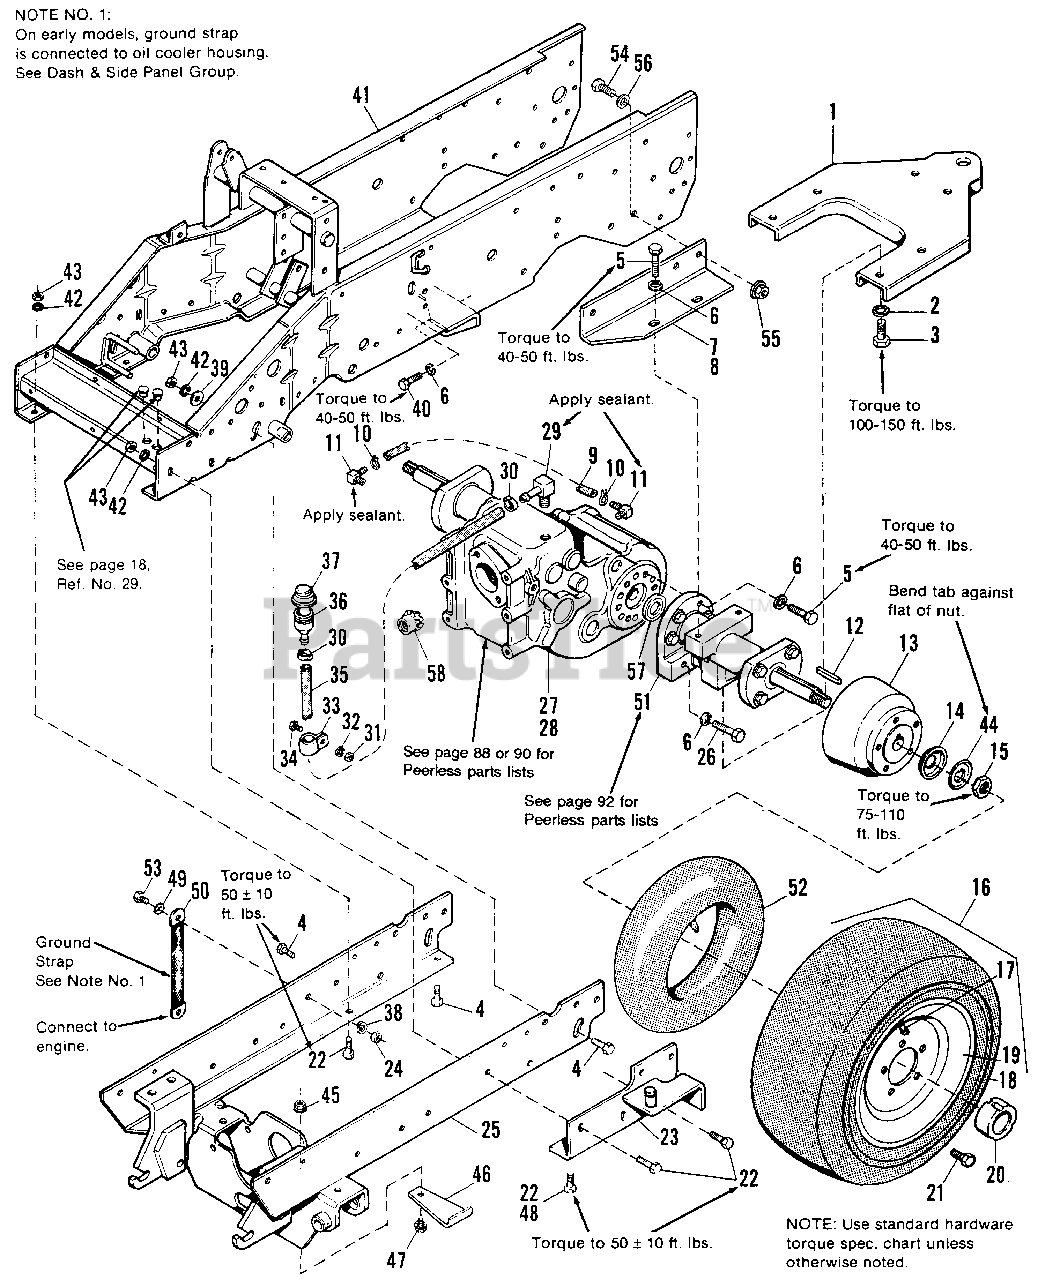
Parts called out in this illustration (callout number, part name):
2	LOCKWASHER, 5/8"
3	CAPSCREW, Hex Hd., 5/8-11 x 1-1/4
4	CAPSCREW, Hex Hd., 7/16-14 x 1, Gr. 5 (Qty. 11 on 1691018, 1691381, 1691528, 1691924)
5	CAPSCREW, Hex Hd., 1/2-13 x 1-1/2
6	LOCKWASHER, 1/2
7	SUPPORT, Transmission, R.H.
8	SUPPORT, Transmission, L.H.
9	HOSE, Fluid Level
10	CLAMP, SAE #6
11	FITTING, Elbow
12	KEY, 5/16 x 5/16 x 2-1/2
13	DRUM, Brake
14	RETAINER, Hub Cap
15	NUT, Hex, Jam Centerlock 1-14
16	WHEEL & TIRE ASSY., 23 x 10.5-12 (Incl. 2 Ref. Nos.17, 18 & 19) (All models except 1691250, 1691357, & 1691953)
16	WHEEL & TIRE ASSY., 23 x 8.5- 12 (Inc. Ref. Nos. 17, 18 & 19) (1691250 & 1691357 only)
16	WHEEL & TIRE ASSY., 26 x 12.00-12 (Inc. Ref. Nos. 17, 18 & 19) (1691953 only)
17	VALVE STEM & CAP
18	TIRE, Turf, 23 x 10.5-12 (All models except 1691250, 1691357 & 1691953)
18	TIRE, Turf, 23 x 8.5-12 (1691250 & 1691357 only)
18	TlRE, Turf, 26 x 12.00-12 (1691953 only)
18	TIRE, Bar Tread (Ag), RH, 26 x 12.00-12 (use only w/60" mower)
18	TIRE, Bar Tread (Ag), LH, 26 x 12.00-12 (use only w/60" mower)
19	WHEEL (all models except 1691953)
19	WHEEL (1691953 only)
22	CAPSCREW, Hex Hd., 7/16-14 x 1-1/4, Gr. 5 (Qty. 5 on 1691018, 1691381, 1691528, 1691710, 1691924, 1691926, 1691928, 1691953 only)
23	BRACKET ASSY., Power Steering Cylinder (Power Steering Models Only)
24	NUT, Hex, 3/8-16 (1691017 & 1691018 only)
25	FRONT FRAME ASSY.
26	CAPSCREW, Hex Hd., 1/2-13 x 2
29	FITTING, Hose, 90
30	CLAMP, Hose, Worm Drive, SAE #10
31	NUT, Hex, 1/4-20
32	LOCKWASHER, 1/4
33	CLAMP, Insulated
34	CAPSCREW, Hex Hd., 1/4-20 x 3/4
35	HOSE, Fill, 1/2" I.D.
36	NECK, Filler
37	CAP, Filler
38	LOCKWASHER, 3/8 (1601017, 1691018 only)
39	WASHER, Plain, 1/2 (1691018, 1691381, 1691528, 1691710, 1691924, 1691926, 1691928, & 1691953 only)
40	CAPSCREW, Hex Hd., 1/2-13 x 1-1/4
41	FRAME ASSY., Rear
42	LOCKWASHER, 7/16 (Qty. 11 on 1691018, 1691381, 1691528, 1691710, 1691924, 1691926, 1691928, 1691953)
43	NUT, Hex, 7/16-14 (Qty. 11 on 1691018, 1691381, 1691528, 1691710, 1691924, 1691926, 1691928, 1691953)
44	RETAINER NUT
45	NUT, Whizlock 3/8-16 (1691017 & 1691018 only)
46	STOP, Axle (1691017 & 1691018 only)
47	SCREW, Whizlock 3/8-16 x 1 (1691017 & 1691018 only)
48	CAPSCREW, 7/16-14 x 1-1/2 (1691018, 1691381, 1691528, 1691710, 1691924, 1691926, 1691928, 1691953 only)
49	WASHER, Ext. Tooth (1691017 & 1691018 only)
50	GROUND STRAP (1691017 & 1691018 only)
52	TUBE, 23" (all models except 1691953)
52	TUBE, 26" (1691953 only)
53	CAPSCREW, 3/8-16 x 1 (1691017, 1691018 only)
54	CAPSCREW, Hex Hd., 7/16-14 x 1-1/4
55	NUT, Hex Flange, 7 / 16-14
56	WASHER, Plain
57	SPACER, Axle
58	GEAR, Bevel
